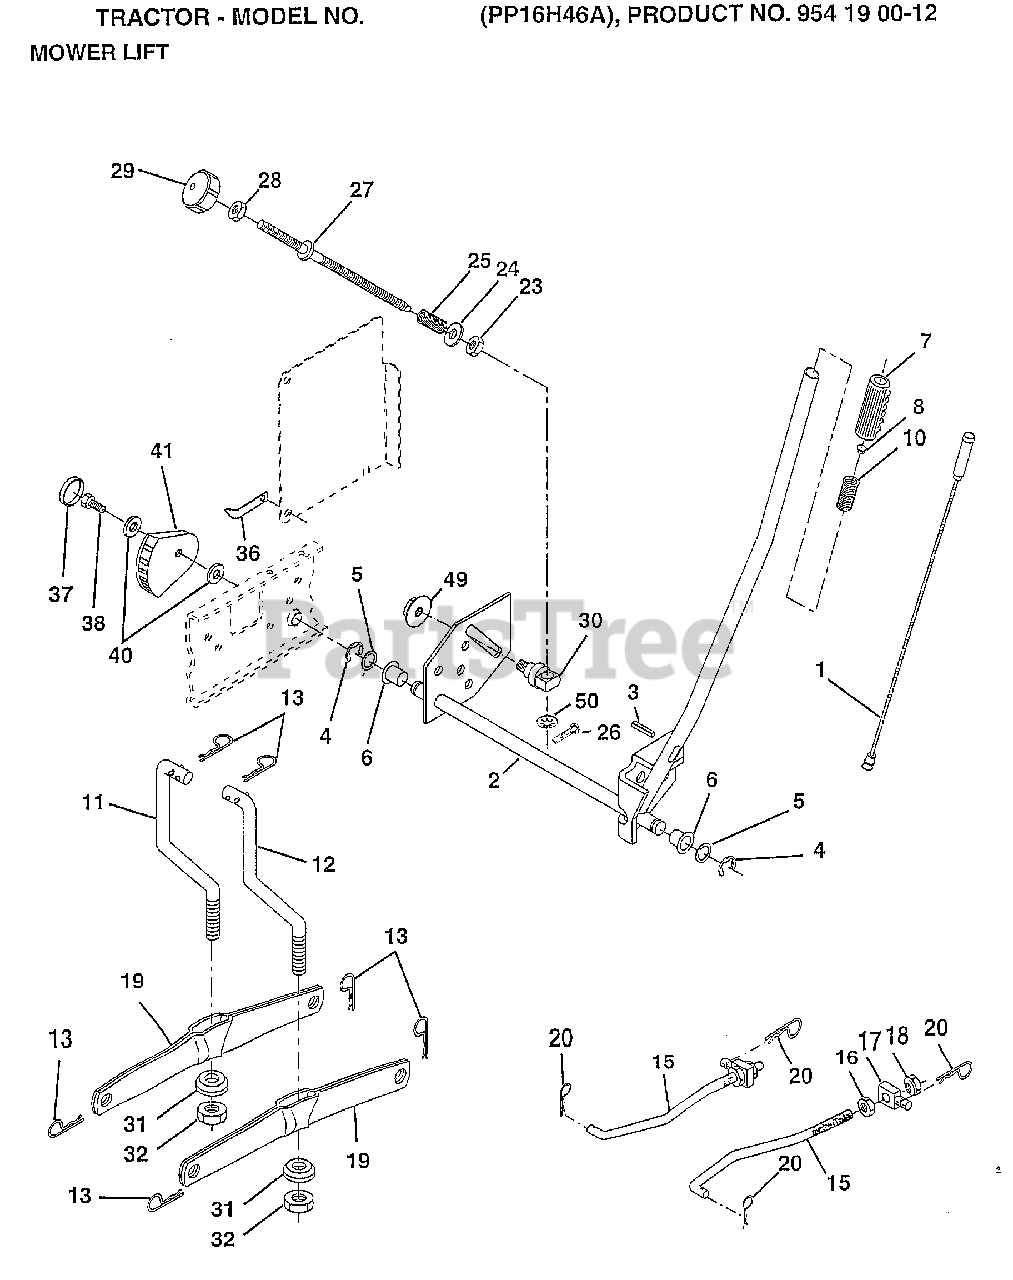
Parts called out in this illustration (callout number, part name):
1	WIRE ASM
2	SHAFT.LIFT.ASM.RH
3	PIN-GROOVE LT
5	WASHER
6	NYLON BEARING
7	GRIP
15	LINK.FRONT
16	NUT
17	TRUNION
18	NUT.LK.W/WSH.1/2.
19	ARM SUSP REAR
20	RETAINER.SPRING
23	NUT T
24	WASHER
25	SPRING T
28	NUT
29	KNOB INF 3/8-16
30	TRUNNION
31	BEARING PVT LH
32	NUT.CROWNLOCK.3/8
36	POINTER-INDICAT
37	"PLUG,HOLE"
38	SCREW
40	WASHER
41	INDICATOR HEIGHT
49	NUT.HXFLG.LOCK.
50	NUT PUSH M
